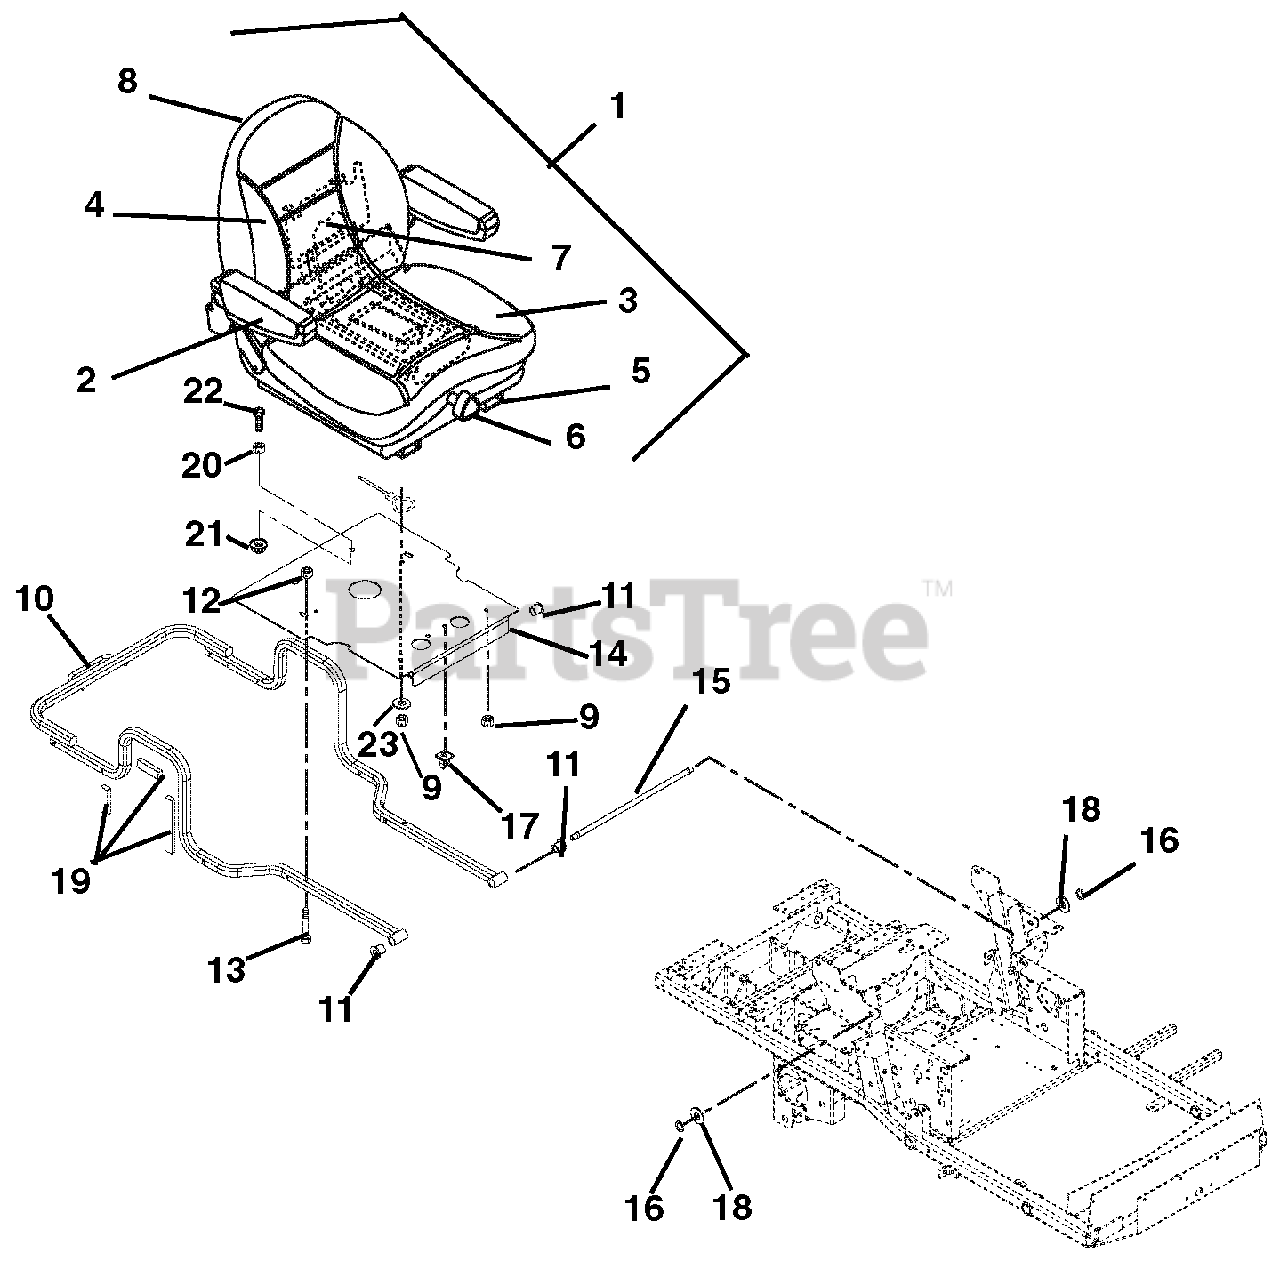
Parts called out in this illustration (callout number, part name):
1	Seat, Suspension, Light Gray
2	Kit, Arm Pad (1 per bag)
3	Kit, Seat Cushion, Light Gray
4	Kit, Back Cushion, Light Gray
5	Kit, Seat Slide
6	Kit, Seat Knob
7	Kit, Spring and Saddle
8	Kit, Seat Back Panel
9	Nut, Locking Top Flange .31-18
10	Weldment, Hood Frame
11	Bushing, Flange .515 x .750 x .745 x 1.00
12	Nut, Locking Top Flange .38-16
13	Bolt, Rib Neck .38-16 x 1.50
14	Weldment, Seat Pivot Mount
15	Rod, Seat Frame Pivot
16	Ring, Retaining External .500 x .050
18	Washer, Flat Steel .531 x 1.06 x .095
19	Tape, VHB
20	Nut, Hex .50-13
21	Nut, Locking Top Flange .50-13
22	Bolt, Hex .50-13 x 1.50
23	Washer, Flat Steel .344 x 1.125 x .135
